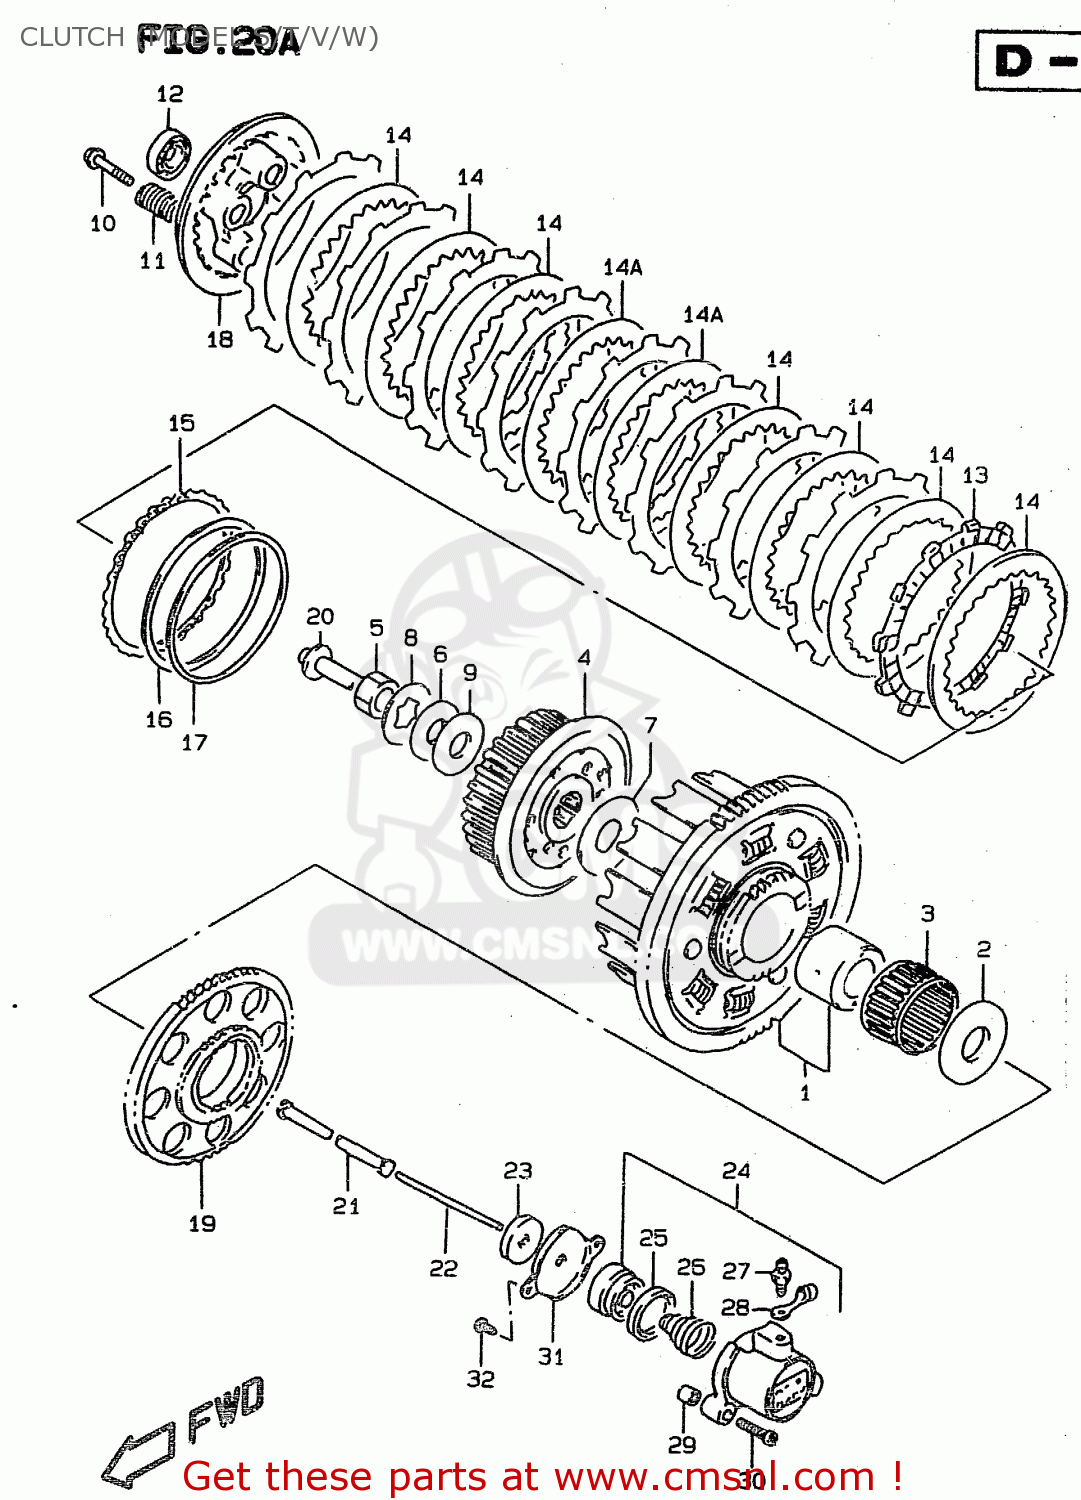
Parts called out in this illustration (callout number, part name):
1	GEAR ASSY,PRI DRIVEN
2	WASHER(25X54X2.5)
3	BEARING(35X40X35.8)
4	HUB,CLUTCH SLEEVE
5	NUT
6	WASHER
7	WASHER(25X50X2.5)
8	WASHER,LOCK
9	WASHER
10	BOLT,CLUTCH SPRING
11	SPRING,CLUTCH
12	BALL BEARING
13	PLATE,CLUTCH DRIVE
14	PLATE,CLUTCH DRIVEN NO.1
14A	PLATE,CLUTCH DRIVEN NO.2
15	PLATE,CLUTCH DRIVE
16	WASHER,CLUTCH PLATE
17	SEAT,CLUTCH PLATE WAVE WASHER
18	DISC,CLUTCH PRESSURE
19	GEAR,GENERATOR DRIVE
20	PIECE,CLUTCH PUSH
21	ROD,CLUTCH
22	ROD,CLUTCH PUSH
23	SEAL,OIL(6X34X5.5)
24	CYLINDER,CLUTCH RELEASE
25	CUP
26	SPRING,CLUTCH CYLINDER
27	BLEEDER
28	CAP,BLEEDER
29	PIN
30	BOLT,CL.COVER
31	COVER,CLUTCH RELEASE CYLINDER
32	SCREW
